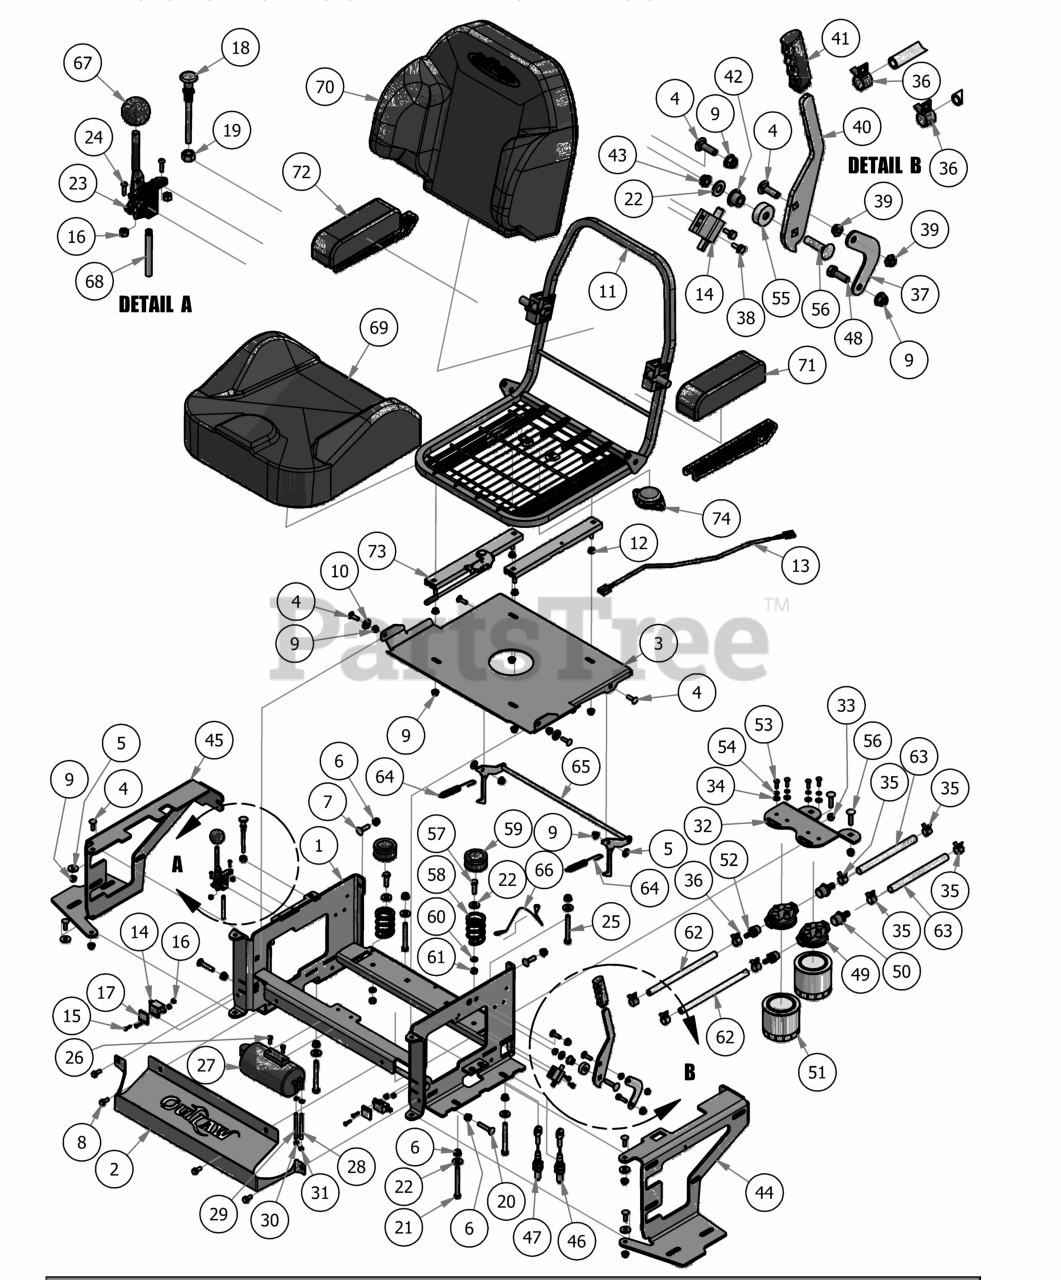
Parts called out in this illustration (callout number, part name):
1	2017 Outlaw Seat Bracket
2	Outlaw Cooler Cover
3	2016 Seat Plate Outlaw
5	.360 ID Plastic Washer
6	3/8" Nylock Flange Nut
7	3/8" x 1 1/4" Carriage Bolt
8	5/16 x 3/4 washer head type F screw
9	5/16" Nylock Flange Nut Zinc
10	.360 ID Plastic Washer-Black
11	2015 Outlaw Seat
12	5/16" Flange Nut
13	Seat Switch Adapter
14	Safety Switch
15	10-24 x 1 BS C/S 18-8 SS
16	10-24 Nylon Insert Locknut
17	Switch Block Plastic
19	3/8" Fine Threaded Jam Nut
20	3/8 x 1 3/4 Carriage Bolt
21	3/8-16x3-1/2 grade 5 hex bolt
22	3/8" Flat Washer
23	Universal Throttle
24	10-24 X 5/8 BS Button Head Bolt
25	3/8-16x3 grade 5 hex bolt
26	M6-1.0 X 16MM Hex Bolt
27	Carbon Canister
28	1/4" Vinyl Tubing
29	3/16 Vinyl Tubing
30	3/16" Vinyl Hose Clamp
31	3/16 Vinyl Clamp
32	Outlaw Filter Bracket
33	3/8 Nylock Nut
34	1/4" Flat Washer
35	1/2 Hose Clamp
36	3/8" Hose Clamp
37	Brake Cable Adapter Bracket
38	12-24x 1/2 HWH Bolt
39	5/16-18 Nylock Jam Nut 1/2 Nut
40	Brake Handle Cam Over
41	Rubber Brake Grip-cZT/ZT 2013
42	Bronze Bushing SF-1220-8
43	3/8 Nylock Jam Nut 1/2 Nut
44	Outlaw 2016 Tank Support (Left)
45	Outlaw 2015 Tank Support (Right)
46	2015 XP Brake Cable - Long
47	2015 XP Brake Cable - Short
48	5/16" x 1" Bolt
49	Filter Head-Hydraulic Filter
50	Filter Head Fitting 1/2 x 1/2
52	1/2" Pipe to 3/8" Barb
53	1/4" x 3/4" Hex Bolt
54	1/4" Lock Washer
55	2015 Brake Lever Spacer
56	3/8 x 1 1/2 Carriage Bolt
57	3/8" x 1 1/4" Hex Bolt
58	Seat Spring
59	Seat Spring Cap Cover
60	3/8" Lock Washer
61	3/8-16 Hex Nuts Zinc
62	3/8" Clear Hose
63	1/2 Clear Braded Hose Priced/Foot
64	Brake Spring
65	Seat Latch Rod Assembly 2016 Models
66	Seat Cable
67	Throttle Knob
68	Outlaw Throttle Cable (Cable Only)
69	Extreme/XP Outlaw Seat Cushion - Bottom
70	Extreme/XP Outlaw Seat Cushion - Back
71	Extreme/XP Outlaw Seat Arm Pads Only (Pair)
72	Extreme/XP Outlaw Seat Arm Rest (Pair)
73	Extreme/XP Outlaw Seat Rails
74	Seat Switch
